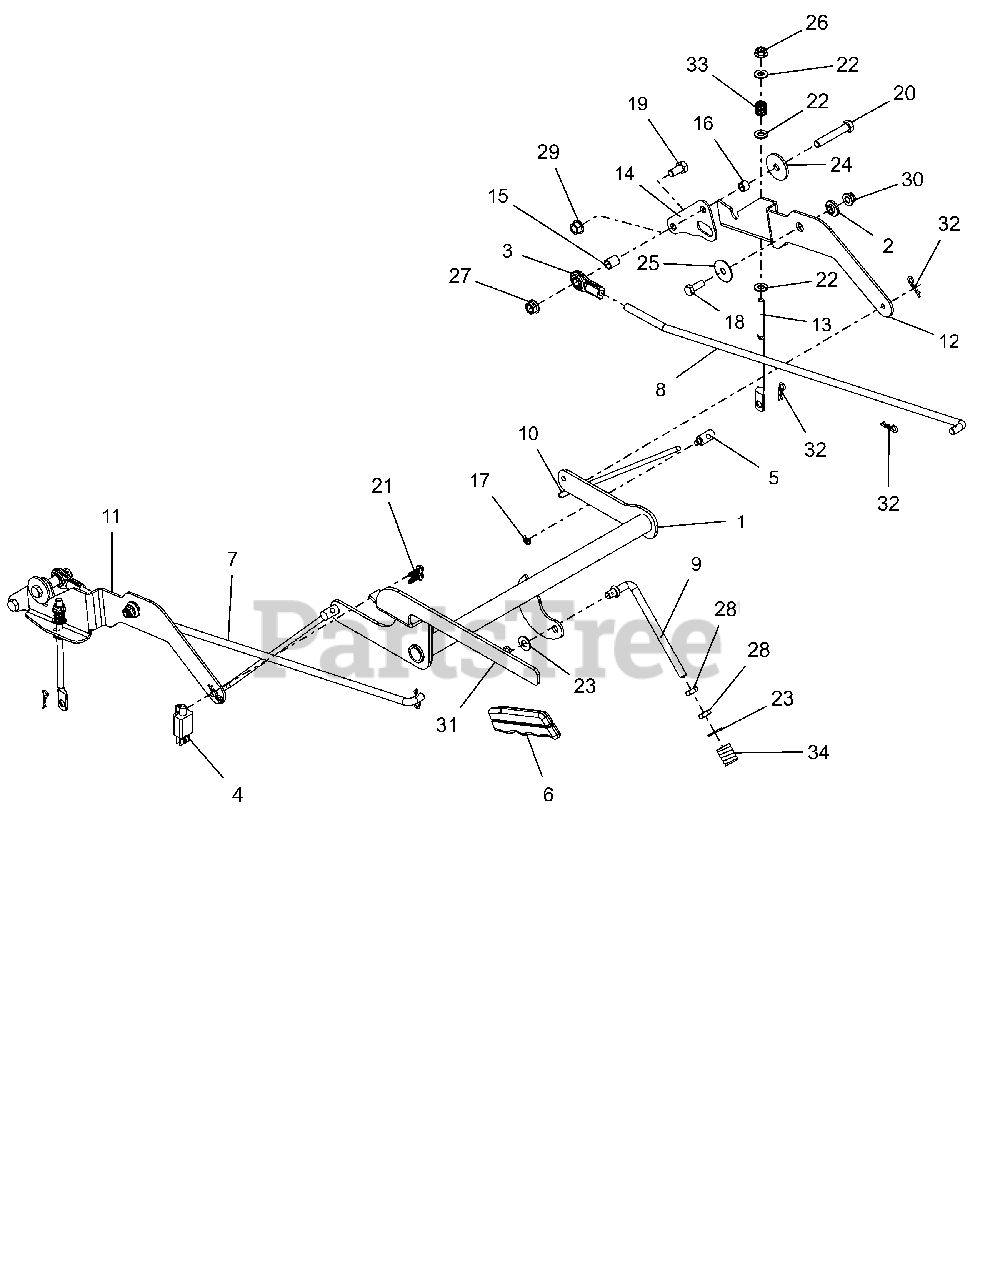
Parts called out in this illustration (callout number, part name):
1	WLDMT, BRAKE LEVER
2	BSHG, FLG .325X.499X.26X.88
3	ROD END, .38 RH
4	SWITCH- DOUBLE POLE N.O./N.O.
5	TRUNION, 1/4-20
6	GRIP, PARKING BRAKE (YELLOW)
7	STEERING, LINKAGE RH
8	STEERING, LINKAGE LH
9	LINK, OVER CENTER, PARKING BRK
10	ROD, PARK BRAKE
11	INTERLOCK, RH BRAKE LINK
12	INTERLOCK, LH BRAKE LINK
13	LINK, TRANSAXLE BRAKE
14	PLATE, TRANSAXLE ADAPTOR
15	SPCR, SLV .385X.500X.652
16	SPCR, SLV .385X.500X.350
17	RG-RTNG-EXT .250X.025
18	BOLT-HEX.31-18X.875 YWZC GR5
19	@BLT-HEX .38-16X.75 GR5 YWZC
20	@BLT-HEX .38-16X2.25 GR5 YWZC
21	SCR-TAP #12X.75 BOSS INDHXHD
22	@WSHR-FL-STL.344X.688X.065YWZC
23	@WSHR-FL-STL.406X.812X.065 YWZ
24	WSHR-FL-STL .380X1.50X.125YWZC
25	WSHR-FL-STL .347X1.254X.048YWZ
26	@NUT-LK-CTR-FLG .31-18 YZ GR F
27	NUT-LK-CTR-FLG .38-16 YWZC
28	NUT-HEX-JAM .375-16 YWZC
29	@NUT-LK-TOP-FLG .38-16 YWZC
30	@NUT-LK-NYL-FLG .31-18 YWZC
31	PIN-HAIR CTR .09 X 1.50 YWZC
32	PIN-HAIR INT .08X.18X1.18 YWZC
33	SPRING, COMPRESSION
34	SG-COMP .187X.56X1.62
